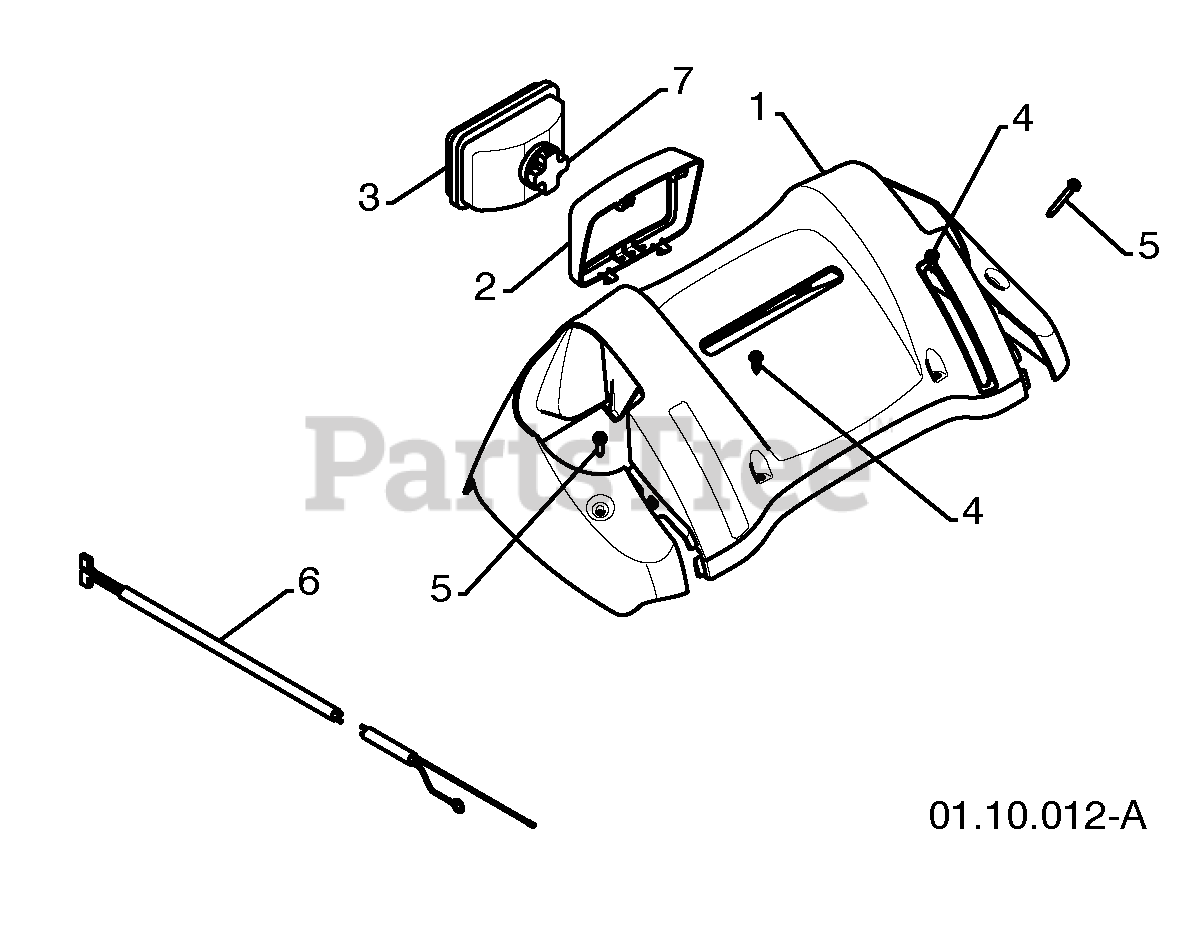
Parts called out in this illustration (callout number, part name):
1	CONSOLE PANEL GRAY
2	HEADLIGHT BEZEL GRAY
3	FLOOD HEADLIGHT
4	SHOULDER SCREW 10-24 X .625
5	SCREW 10-24 X 1.25
6	WIRE HARNESS
